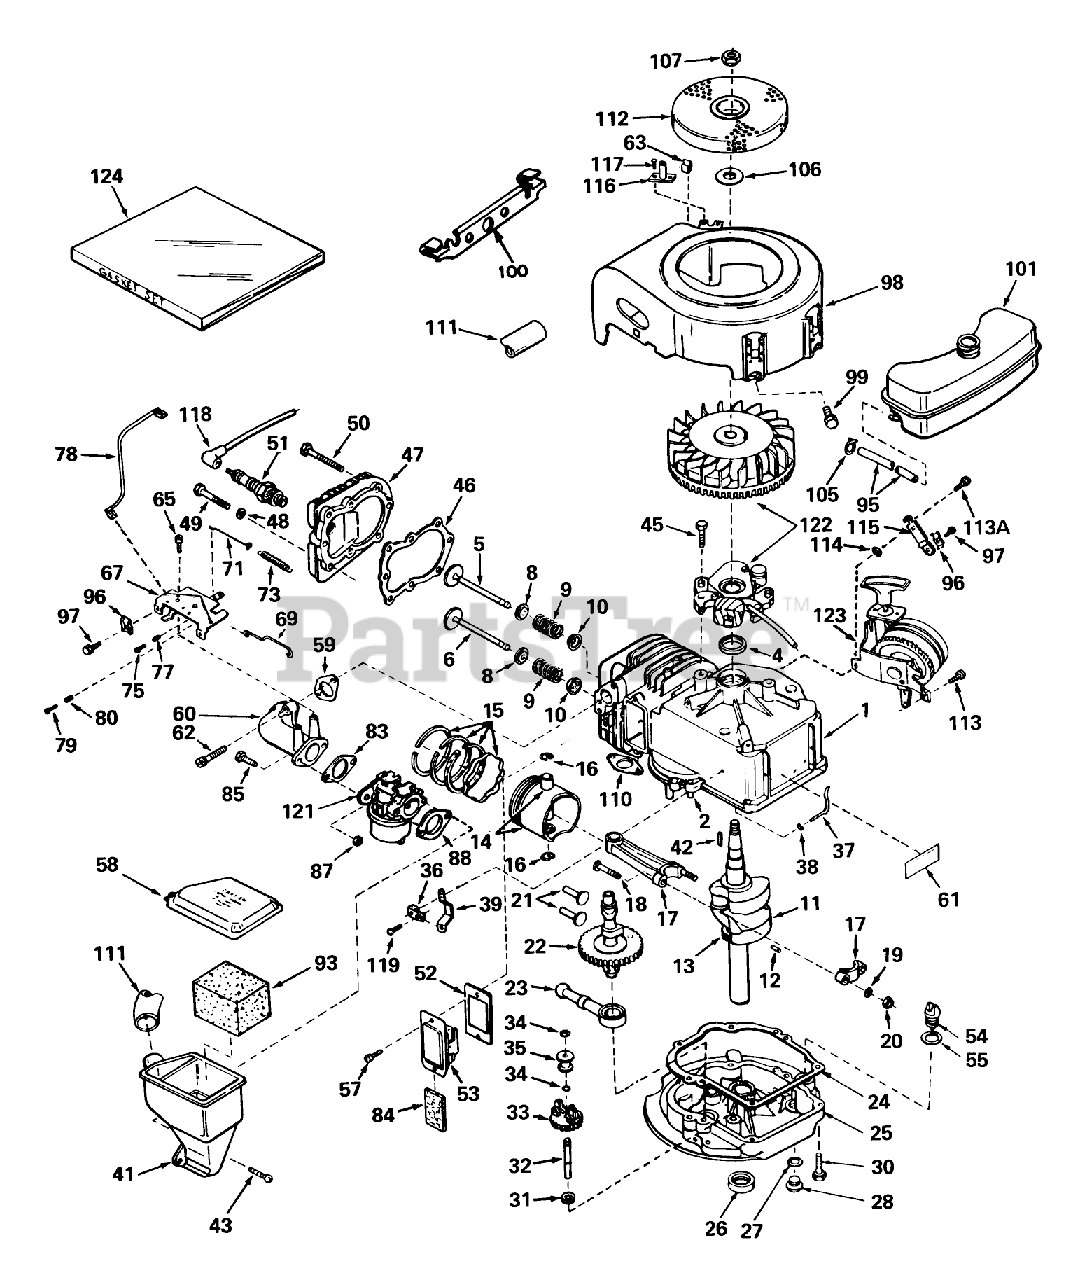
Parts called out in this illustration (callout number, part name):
1	Cylinder Assembly (Incl. Nos. 2, 4 113)
2	Pin-Dowel
4	OIL SEAL
5	Valve, Intake (Incl. Ref. #38, 39 40) (Std.)
5	Valve, Exhaust (1/32" Oversize) (Incl. Nos. 8, 9 10)
6	Valve, Exhaust (Standard) (Incl. Nos. 8, 9 10)
6	Valve, Exhaust (1/32" Oversize) (Incl. Nos. 8, 9 10)
8	Cap-Upper Valve Spring
9	Spring-Valve
10	Cap-Valve, Spring
11	Crankshaft Assembly (Incl. Nos. 12 13)
12	Pin, Groove
13	Gear, Crankshaft
14	Piston Pin Assembly (Incl. 2 of No. 16) (Std.)
14	Piston Pin Assembly (Incl. 2 of No. 16) (.010 Oversize)
14	Piston Pin Assembly (Incl. 2 of No. 16) (.020 Oversize)
15	Piston Ring Set Std.
15	Piston Ring Set .010 O.S.
15	Piston Ring Set .020 O.S.
16	Ring-Retaining, Piston Pin
17	Rod Assy., Connecting (Incl. Ref. #17)
18	Bolt, Connecting
19	Washer
20	LOCKNUT
21	Lifter-Valve
22	Camshaft (Compression Release
23	Oil Pump ASM
24	Gasket, Mounting
25	Flange Assembly, Mounting (Incl. Nos. 26 32)
26	Seal Oil
27	Gasket-Oil Drain
28	Plug Oil Drain
30	Screw (1/4-20 x 1-1/4)
31	Washer-Flat
32	Shaft-Governor
33	Governor Gear ASM
34	Ring-Retaining
35	Spool-Governor
36	Clamp-Lever, Governor
37	Rod, Governor (Incl. No. 36)
38	Washer-Flat
39	Governor Lever
41	Body, Air Cleaner
42	Key Flywheel
43	Screw, Fil. Hd. Sems
45	Screw
46	Gasket-Cylinder Head
47	CYLINDER HEAD
48	Washer
49	Screw
50	Screw Hex Hd. Cap
51	Plug, Spark (J17LM or equiv.)
52	Gasket Breather
53	Breather Assembly (Incl. Nos. 52 84)
54	Plug-Fill, Oil
55	Gasket
57	Screw
58	Cover, Air Cleaner
59	Gasket, Intake
60	Pipe, Intake
61	480B GIL SNWTHWR O/
62	Screw (1/4-20 x 1)
63	51004 GIL ROTARY TI
65	Screw (10-24 x 9/16)
67	51089 SUPP TO MANUA
69	Link Governor
71	Link-Governor
73	Spring, Governor
75	Screw
77	Spring-Compression
78	Wire, Ground
79	Screw
80	61709/GIL1515A/95-5
83	Gasket
84	Element-Breather
87	Nut and Lock Washer (1/4-28)
88	Gasket-Air Cleaner
93	Element, Air Cleaner
95	Line-Fuel (8.62)
96	Conduit
97	Screw (10-32 x 3/8)
98	Housing, Blower
99	Screw (1/4-20x19/32)
100	Bracket, Shroud
101	Tank, Fuel
102	Cap, Fuel Filler
105	Clamp-Line, Fuel
106	Washer
107	Nut, Flywheel
110	Gasket Exhaust
111	Tube, Air Cleaner
112	Screen, Flywheel
113	Screw (1/4-20 x 1/2)
113A	Screw (1/4-20 X 5/8)
114	Washer
115	Bracker
116	Guide Assembly, Rope
117	Rivet
118	Cover-Spark Plug
119	Screw
121	Carburetor (Incl. No. 83)
122	Magneto
123	Starter
124	Gasket Set
